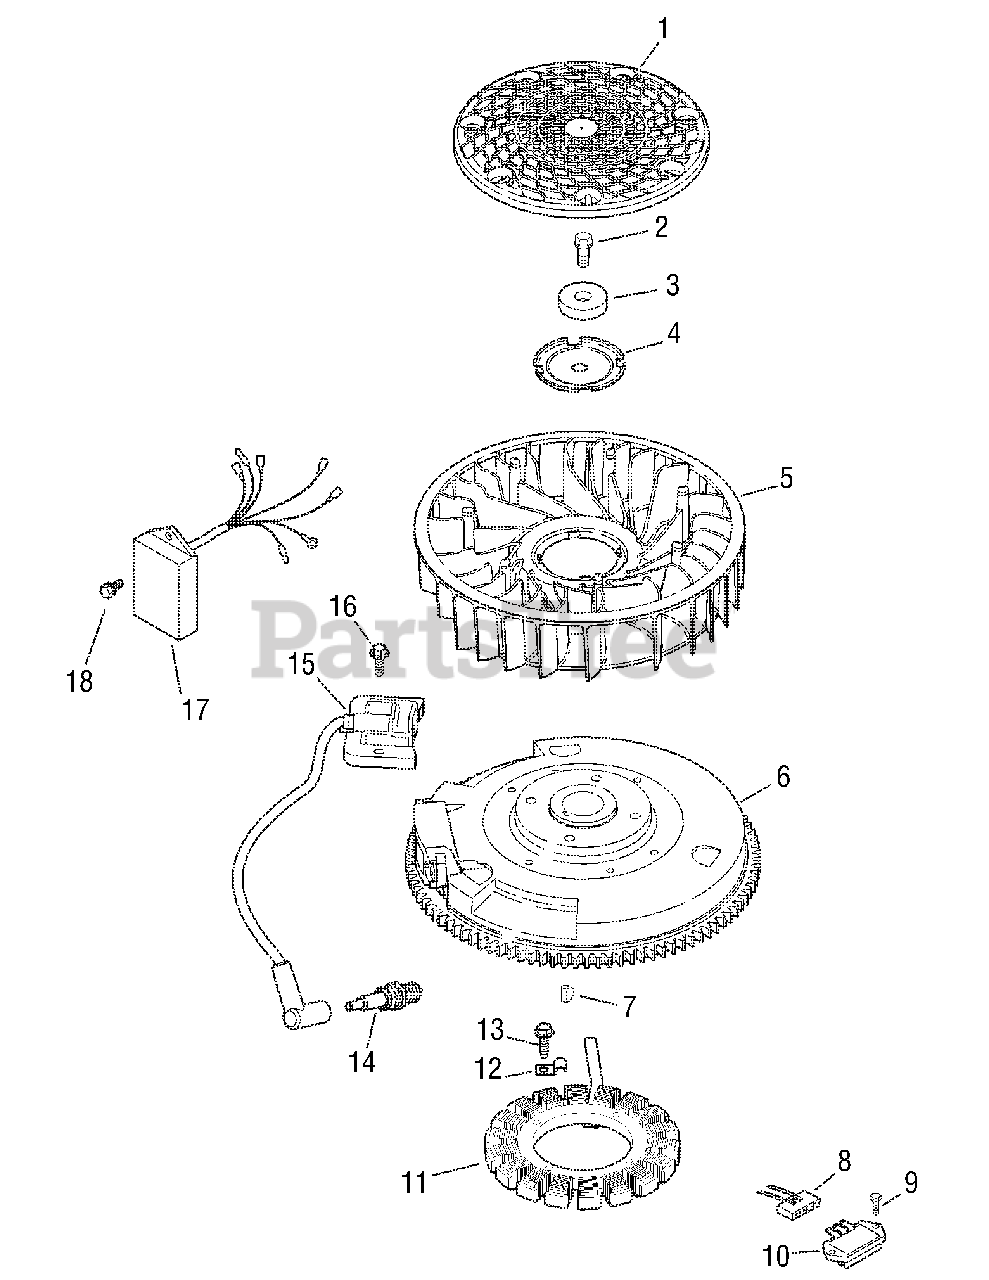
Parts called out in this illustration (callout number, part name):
1	Screen, grass
2	Screw, hex. flange M10x1.5x45
3	Washer, plain 3/8"
4	Plate, fan mounting
5	Fan
6	Flywheel
8	Rectifier-regulator
9	Connector (3 contact)
10	Screw, heavy hex. flange M5x0.8x16
11	Kit, 15 amp stator
13	Screw, hex. head thread forming M5x0.8x25
14	Spark plug
15	Module, ignition
16	Screw, hex. flange thread forming M5x0.8x20
17	Module, speed advance
18	Screw, hex. flange thread forming
